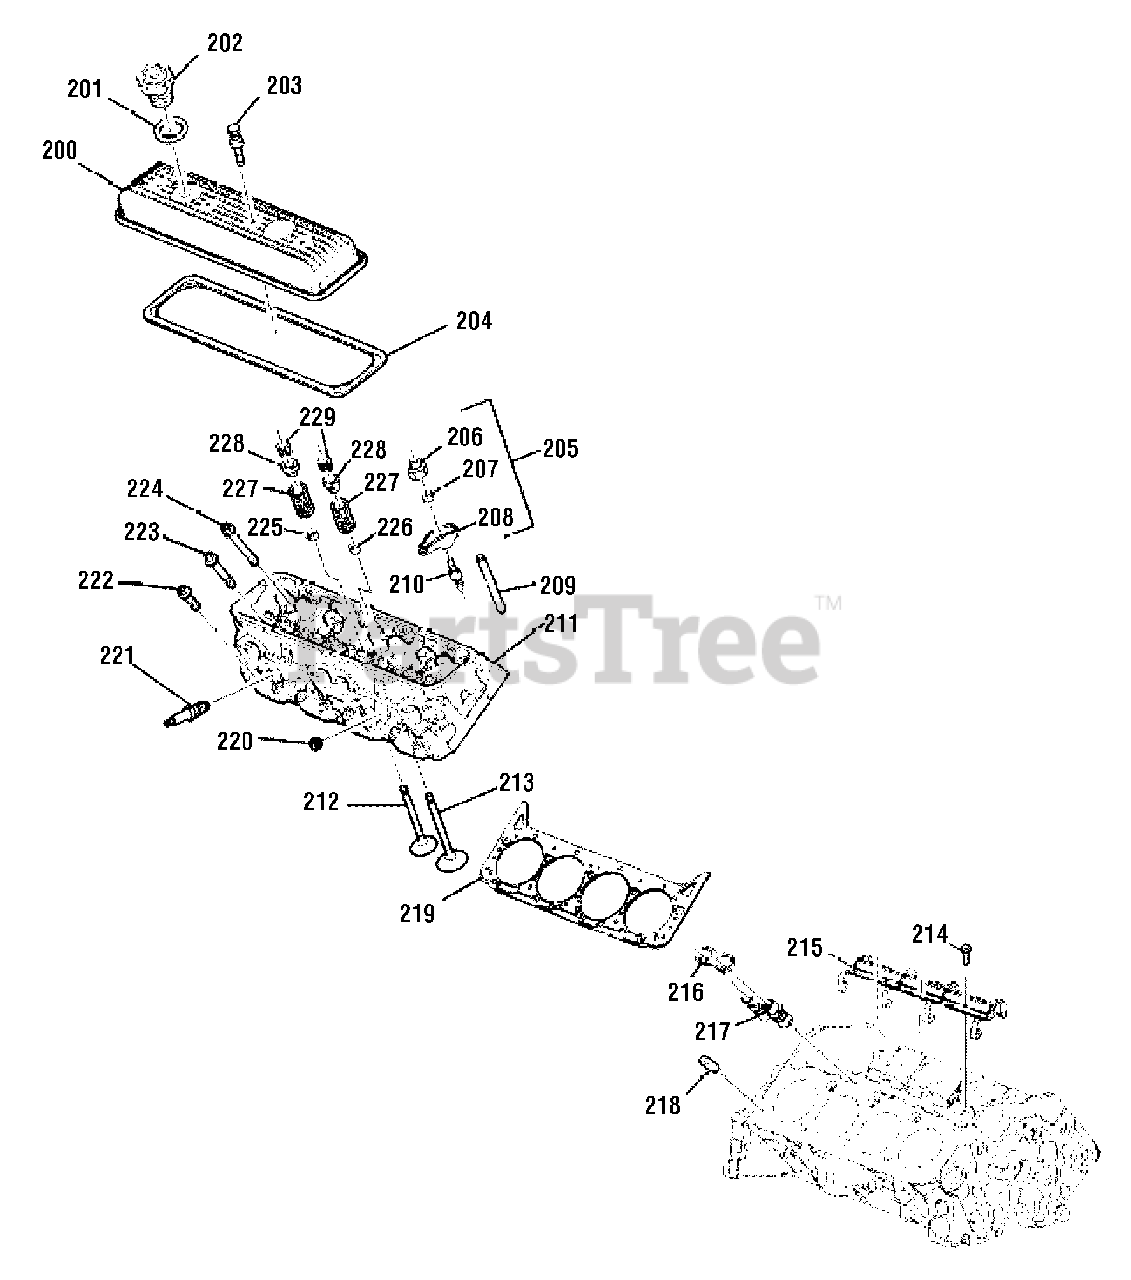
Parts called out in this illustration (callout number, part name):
200	* COVER
201	* SEAL
203	* BOLT
205	* KIT
206	* NUT
207	* BALL
208	* ARM
209	* ROD
210	* STUD
211	* HEAD
211	* HEAD HD (OPTIONAL)
212	* EXHAUST VALVE
213	* INTAKE VALVE
214	* BOLT
215	* RETAINER
216	* GUIDE
217	* LIFTER
218	* PIN
220	* PLUG
222	* BOLT
223	* BOLT
224	* BOLT
225	* SEAL
226	* SEAL
227	* SPRING
228	* CAP
229	* KEY
